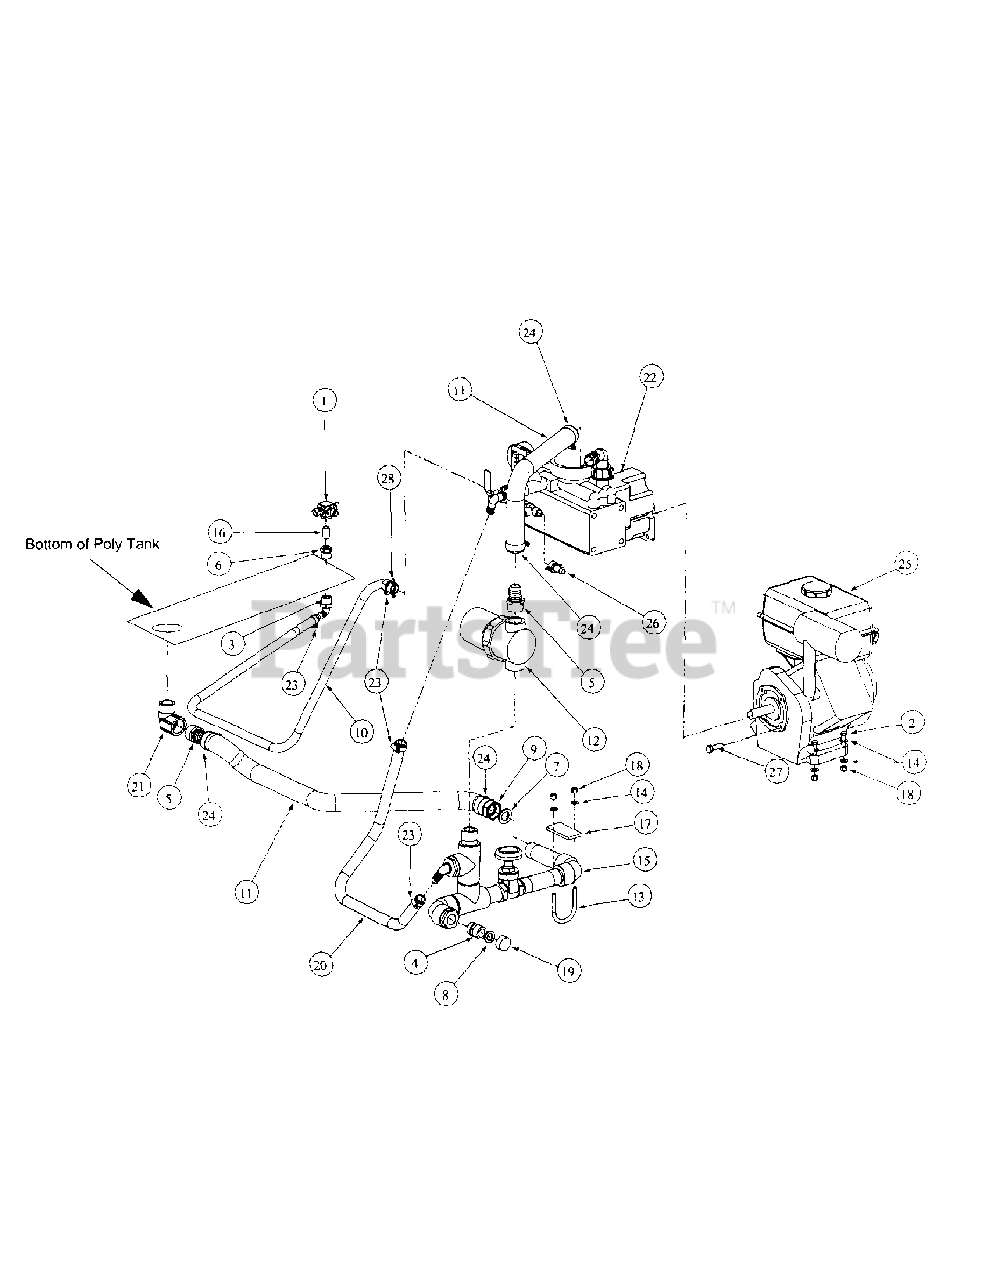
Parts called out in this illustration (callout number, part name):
1	Agitator, Jet
2	HHCS, 5/16-18, 1-3/4
3	Hose Barb, 1/2 NPT, 1/2 Nylon
4	Adapter, 3/4 NPT, 3/4 Hose
5	Hose Barb, 1" NPT, 1" Nylon
6	Adapter, 1/4 NPT, 1/2 NPT
7	Washer, Hose 1"
8	Washer Hose, 3/4" Rubber
9	Repair Coupling, Hose
10	Hose, 1/2" sold by the ft.
11	Hose, 1", Spiraflex sold by the ft.
12	Strainer, 30 Mesh-SS
13	U-Bolt, 5/16-18 x 2
14	Flat Washer, 5/16 SAE
15	Manifold Assembly
16	Nipple, 1/4 NPT
17	Rubber Pad 1/4" x 1-1/2" x 3"
18	Nut, 5/16-18, Nylock
19	Hose Cap, 3/4"
20	Hose 5/8" PVC sold by the ft.
21	Street Elbow, PVC 1" NPT x 1"
22	Pump Assembly
23	Hose Clamp, 1/2, 7/8
24	Hose Clamp, 7/8, 1-1/4
25	Engine, 5.5HP Kawasaki
26	Fittings
27	Button Head Bolt, m8-1.25 x 25 mm
